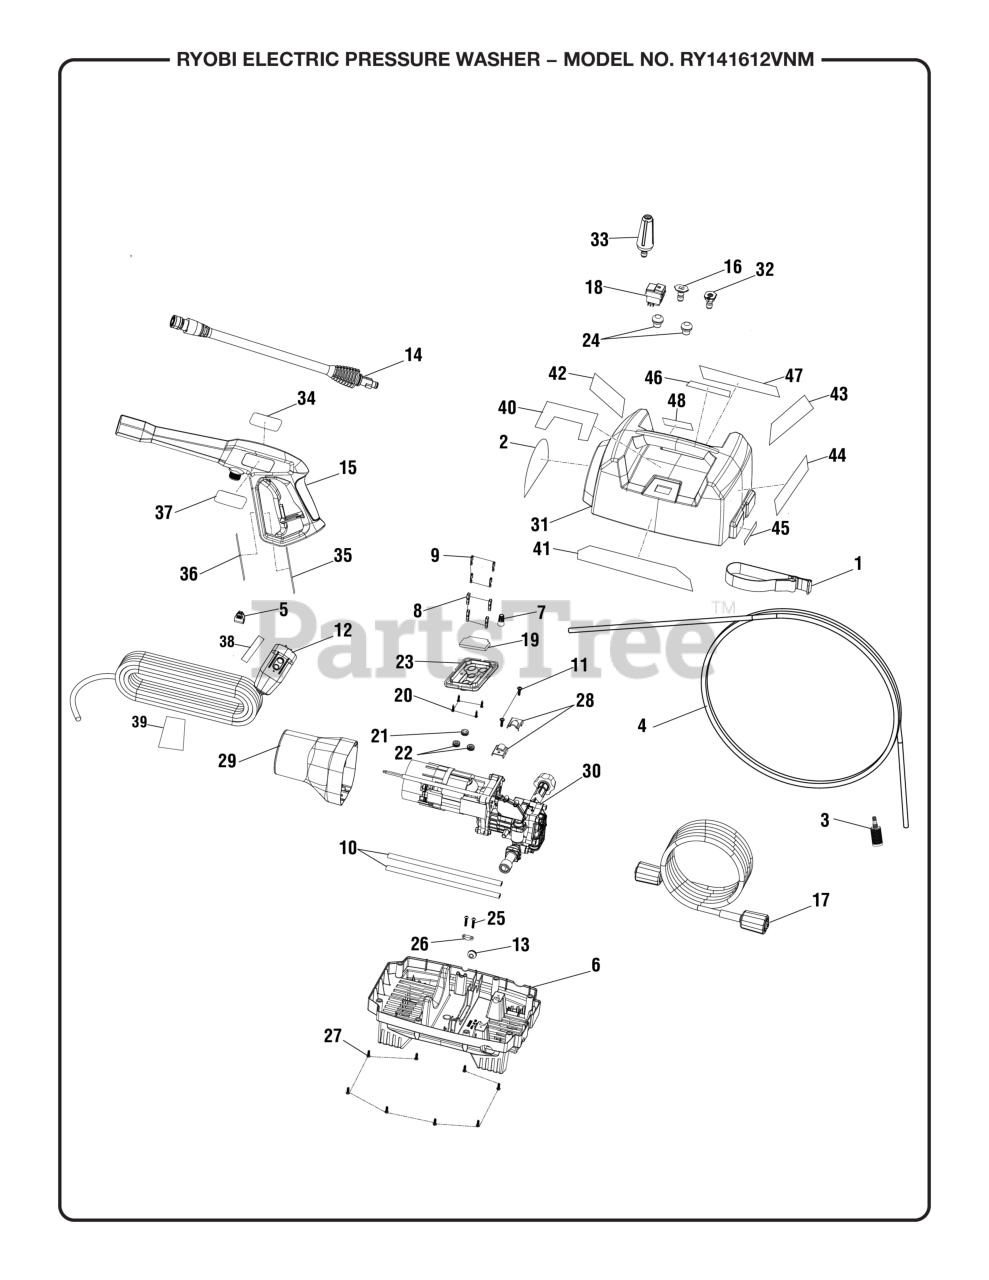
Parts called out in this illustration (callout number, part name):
1	Hose Storage Strap (Velcro)
2	Regulatory Danger Label
3	Detergent Injection Filter
4	Detergent Injection Tube
5	Electric Cord Clip
6	Lower Housing
7	Tuerca para alambre
8	Plastic Sleeve (Terminal)
9	Tinned Brass (Terminal)
10	Terminal Sleeve
11	Screw w/ Washer (M4 x 16 mm, Round Hd.)
12	Power Cord Assembly
13	Housing Rubber Grommet
14	Spray Wand Assembly
15	Trigger Handle Assembly
16	Soap Nozzle (Blue)
17	High Pressure Hose
18	On/Off Switch
20	Screw (M2.9 x 14 mm, Pan Hd.)
21	Housing Rubber Grommet
22	Nozzle Grommet
23	Switch Cover
24	Nozzle Grommet
25	Screw (M3.5 x 20 mm, Button Hd.)
26	Cord Clamp
27	Screw (M4.2 x 15 mm, Phillips Hd. S.T.)
28	Motor Clamp Plate
29	Air Shourd
30	Motor and Pump Assembly
31	Upper Housing
32	15deg Nozzle
33	Turbo Nozzle
34	Trigger Handle Label (Logo Label)
35	Trigger Handle Warning Label (French/Spanish)
36	Trigger Handle Data Label
37	Trigger Handle Warning Label (English)
38	Warning Label (Cord Wrap)
39	Power Cord Label
40	On/Off Label
41	Performance Label
42	Nozzle Hangtag (PS141913)
43	Danger Hangtag (Spanish)
44	Danger Icon Label (English/French)
45	Soap Tube Attachment Label
46	Nozzle Selection Label
47	Starting Instructions Label
48	Inquires Label (Ryobi)
